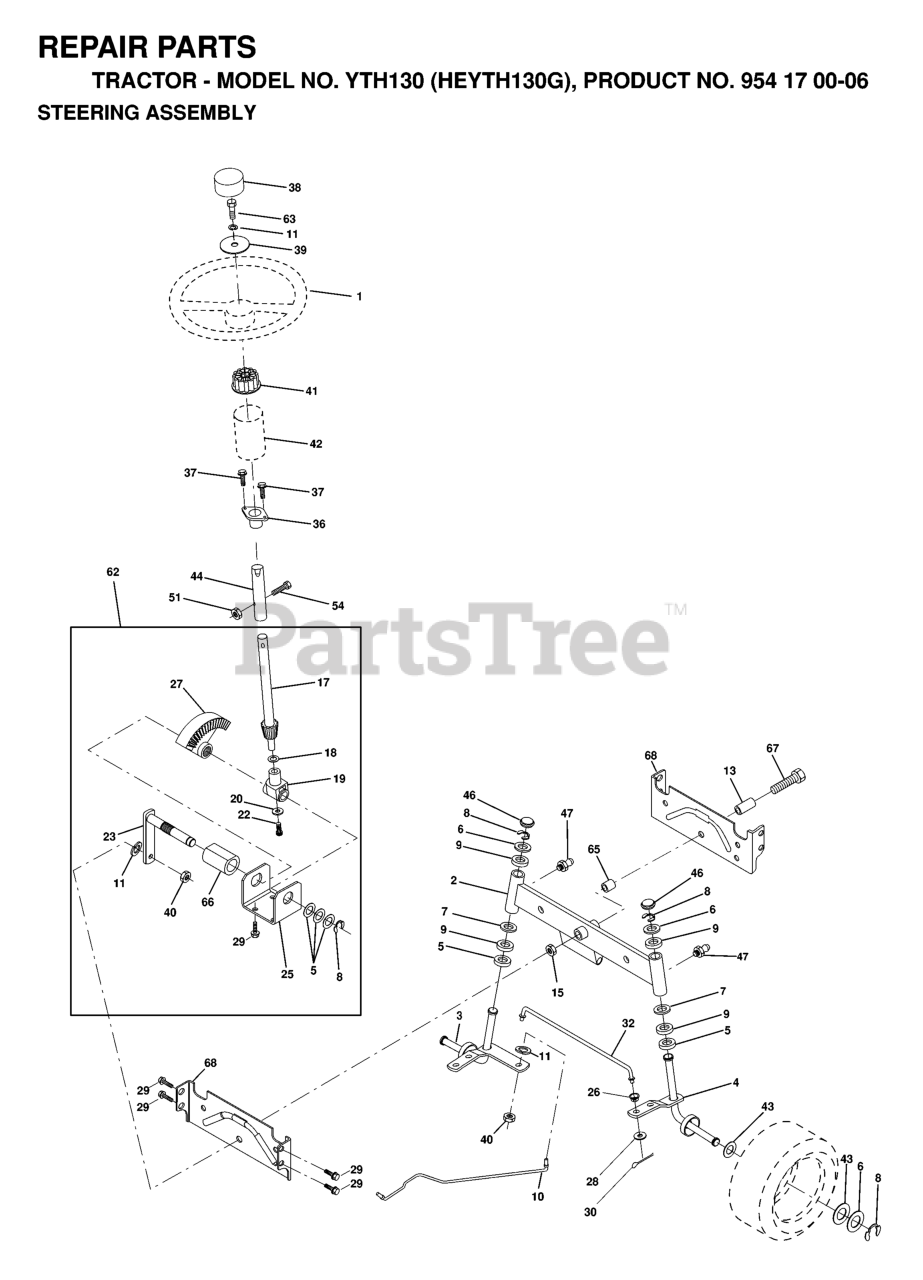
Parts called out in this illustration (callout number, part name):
1	STEERING WHEEL
2	AXLE ASSY
3	SPINDLE ASM LH
4	SPINDLE ASM RH
5	THRUST WASHER
9	BRNG T
10	DRAGLINK-STAMPED
11	WASHER, LOCK 3/8
13	BEARING AXLE
15	NUT-LOC,FLANGE LT
17	SHAFT ASM STEERING
18	THRUST WASHER
19	SHAFT,SUPPORT
20	WASHER
22	SCREW HEX SOCKET 1/4-20 X 5/8
23	SHAFT PITMAN
25	BRACKET STEERING
26	BUSHING.DRAGLINK (2 2)
27	GEAR.SECTOR
28	WASHER
29	SCREW
30	COTTER PIN
32	TIE ROD
36	BUSHING, STEERING
37	SCREW.TT.#10-32X.5.3/8.FLANGE
38	INSERT,STR WHEEL
39	WASHER T
40	GRIPCO NUT
41	ADAPTER LT
42	BOOT, STEERING
44	EXT SHAFT STEERING
46	CAP.SPINDLE.BLACK
47	ZERK M
51	NUT.71038.31-18.HEX.NYLOCK
54	BOLT.5/16-18X1-1/4 FULL.THREAD
62	KIT, STEERING ASSEMBLY
65	SPACER AXLE
66	BEARING ARM
67	Bolt, Hex 5/8 -11 x 2 - 3/4 Gr. 5
68	AXLE, BRACE
